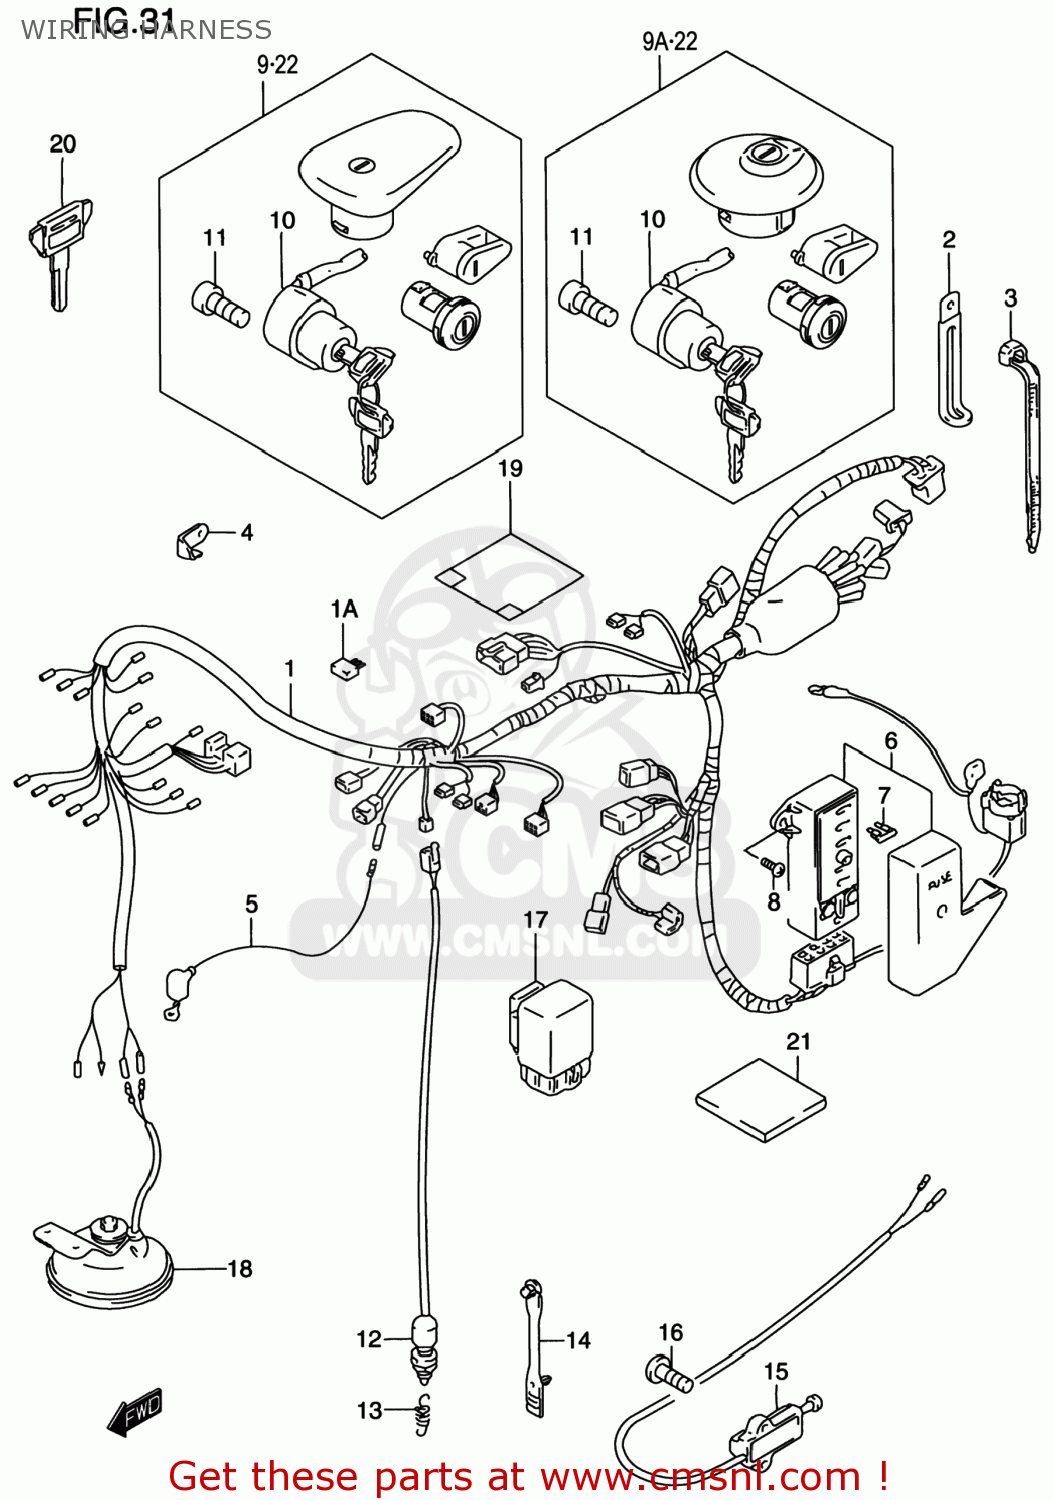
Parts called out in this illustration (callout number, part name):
1	HARNESS,WIRING
1A	DIODE(STANLEY DE8804)
2	CLAMP(L:45)
3	CLAMP L:165
4	PLATE,COUPLER HOLDER
5	WIRE,WATER TEMP GAUGE LEAD
6	BOX ASSY,FUSE
7	FUSE(10A)
8	SCREW
9	LOCK SET
9A	LOCK SET
10	SWITCH ASSY,IGNITION
11	BOLT
12	SWITCH ASSY,STOP LAMP
13	SPRING
14	CLAMP,L:88
15	SWITCH ASSY,SIDE STAND
16	SCREW
17	RELAY ASSY
18	HORN ASSY
19	COVER,WIRING HARNESS
20	KEY,BLANK(TYPE:C)
21	COVER,HARNESS
22	LOCK SET
